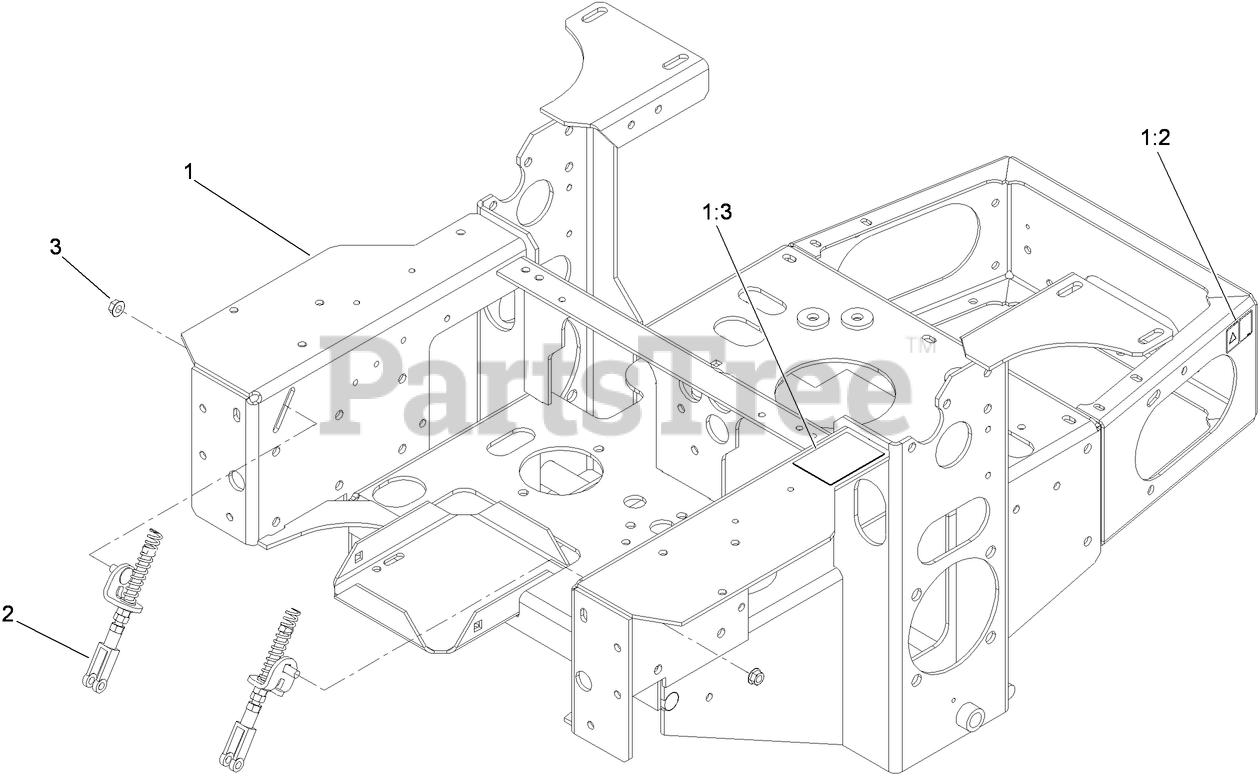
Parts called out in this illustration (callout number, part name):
1	MAIN FRAME ASM (W/ DECALS CE)
1:2	DECAL-WARNING
1:3	Decal-Release, Drive
2	NEUTRAL RETURN ASM
3	NUT-HF
